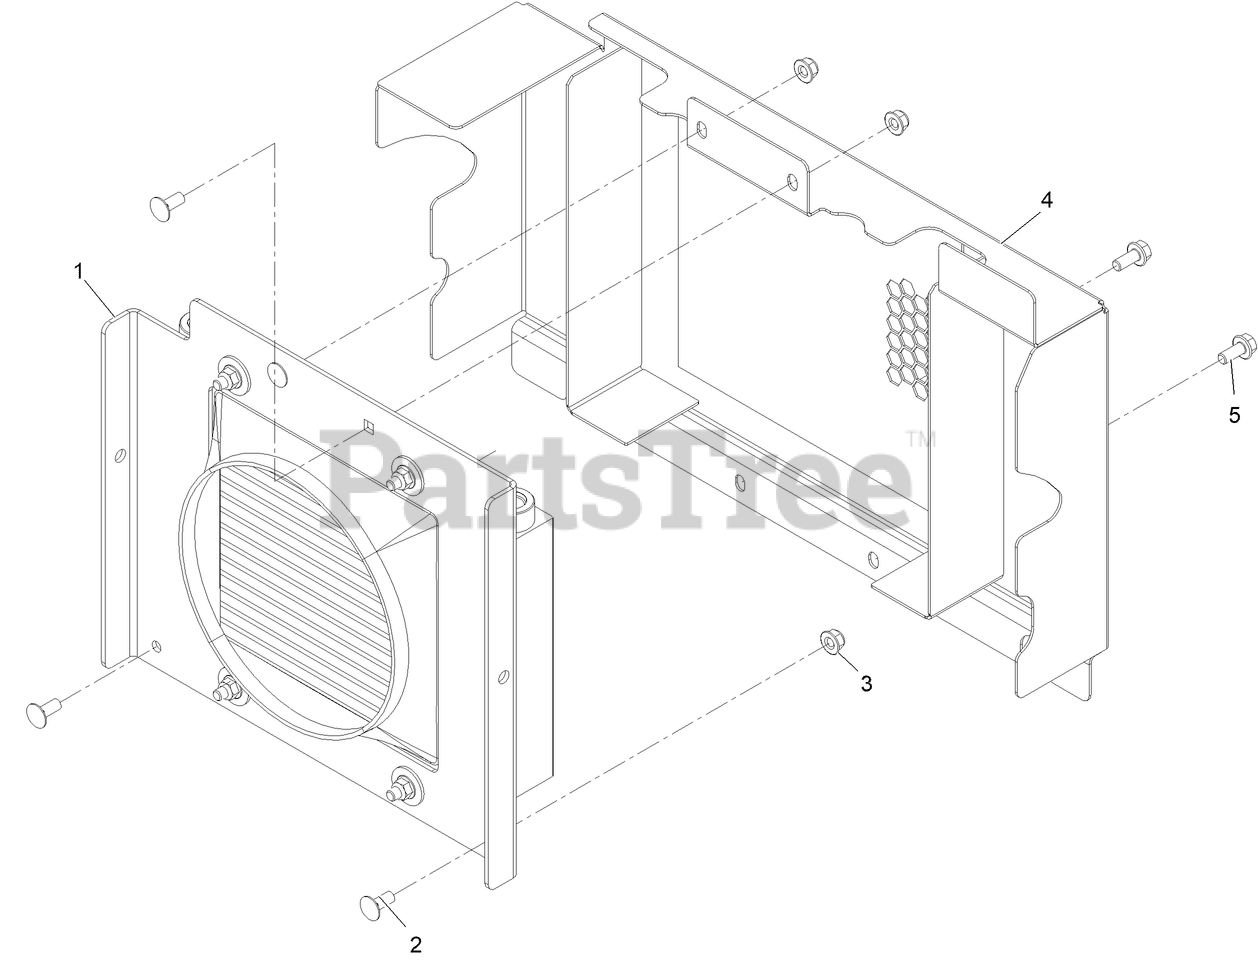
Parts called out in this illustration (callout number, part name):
1	Oil Cooler ASM
2	SCREW-CARR
3	NUT-HF, NI
5	SCREW-HHF
